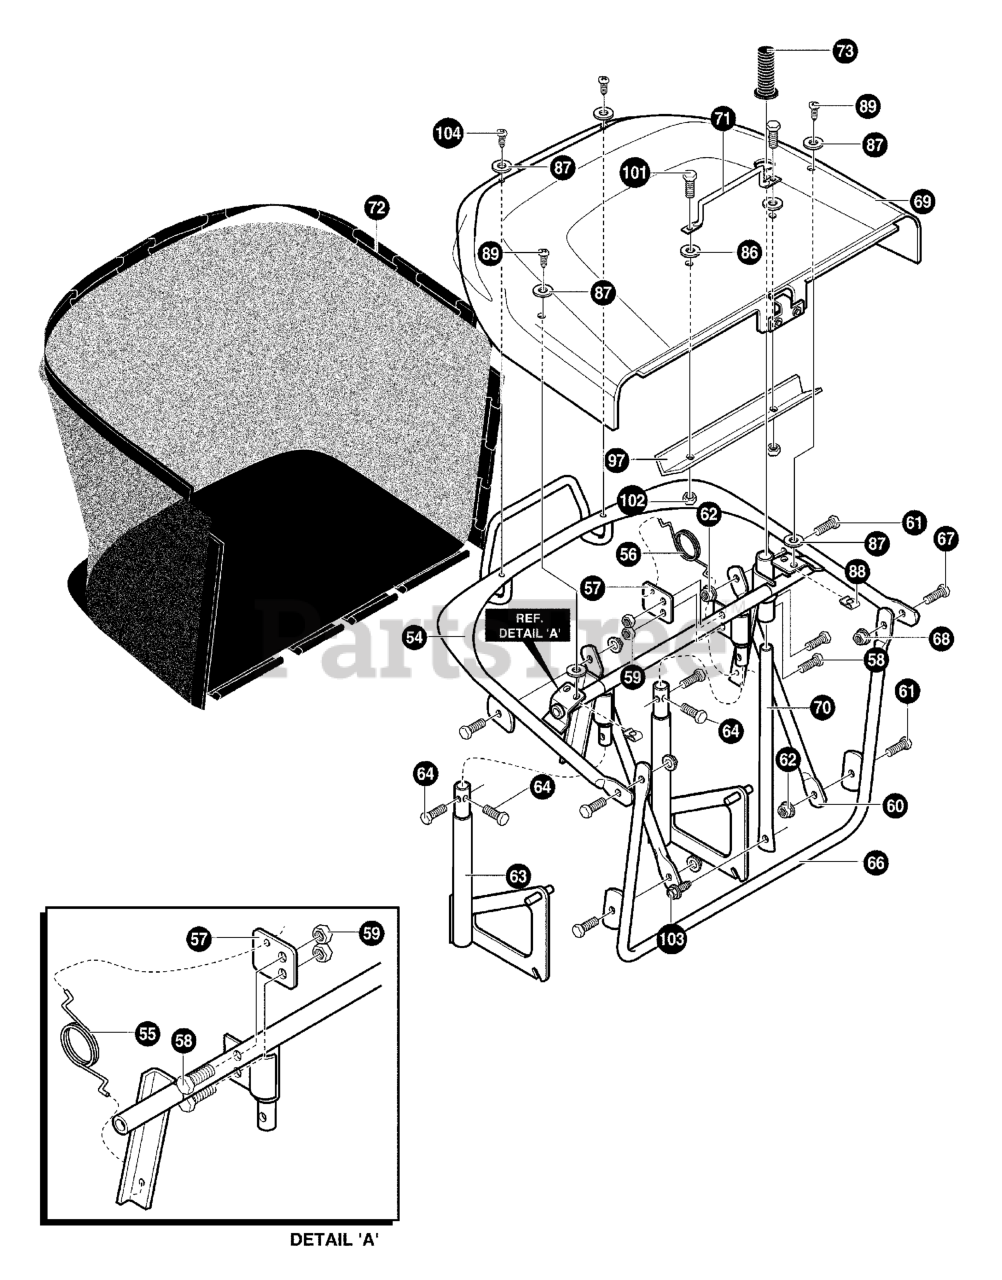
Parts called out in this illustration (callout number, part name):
54	ASM. WLD- UPPER FRAME
55	SPRING, TORSION RH BAG CLOSE
56	SPRING, TORSION LH BAG CLOSE
57	BRACKET, SPRING COLLECTOR
58	SCREW, 1/4-20X.50
59	NUT, 1/4-20 REGHEXCTRLK
60	BRACE, FRAME COLLECTOR
61	SCREW, 1/4-20X.62
62	NUT, 1/4-20 HEXNYL
63	ASM. SUPPORT COLLECTOR
64	SCREW, 5/16-18 x 1.50
66	ASM., FRONT FRAME COLLECT
67	SCREW, 1/4-20X.62
68	NUT, 1/4-20 HEXNYL
69	TOP COLLECTOR ASM.
70	HANDLE, DUMP REBA COLLECTOR
71	HANDLE, REBA COLLECTOR
72	REBA COLLECTOR BAG
73	RUBBER GRIP
85	NUT, 5/16-18WDFLLK
86	WASHER, .281X1.25X.06
87	WASHER, FLAT .328X1.06X.062
88	NUT, 1/4-20 TINN U
89	SCREW, 1/4-20X.63 PHPNHD
97	BRACE, BAGGER
101	SCREW, 1/4-20X1.50 SLHWATAP
102	NUT, 1/4-20 HEXNYL
103	SCREW, #12X.50 PHPNHTAP
104	SCREW, #12X.50 PHPNHTAP
